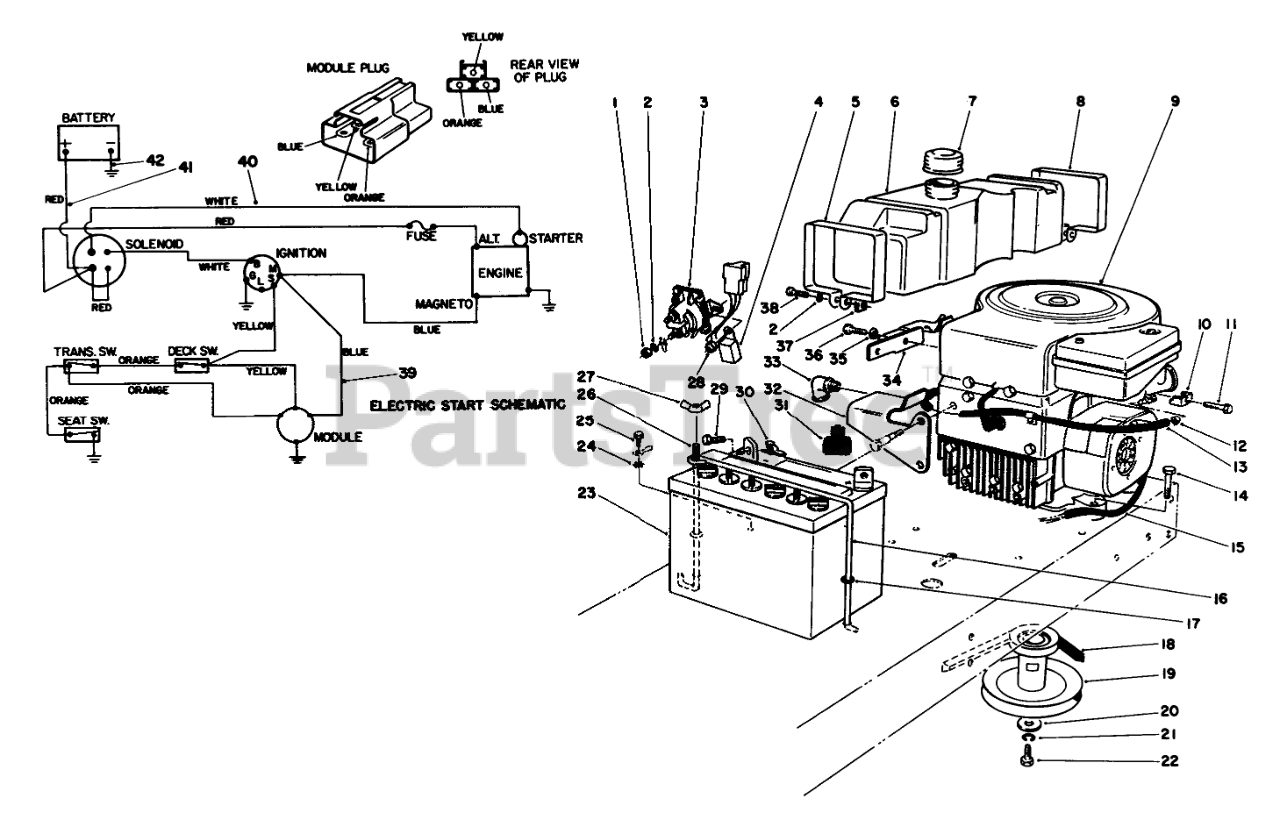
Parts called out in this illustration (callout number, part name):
1	NUT-JAM
2	WASHER-LOCK
3	SOLENOID
4	Module Interlock
5	Retainer-Front
6	TANK-5 QT GAS
7	GAS CAP ASM
8	Retainer-Rear
9	Engine
10	CLAMP-CASING
11	SCREW W ENGINE
12	FUEL HOSE CLAMP
13	HOSE-FUEL
14	SCREW-HH
15	HEAT SHRINK TUBING
16	HOLDDOWN-BATTERY
17	O-RING
18	V-BELT, TRACTION
19	PULLEY
20	WASHER-FLAT
21	WASHER-LOCK
22	SCREW-HH
23	Battery
24	WASHER-LOCK, INTERNAL
25	SCREW-HHF
26	POST-BATTERY
27	NUT-WING
28	NUT-LOCK, CONE
29	SCREW-HH
30	NUT-WING
31	BOOT-TERMINAL
32	FRT TANK MTG BRKT B
33	ELBOW-STREET, 90 DEG
34	REAR TANK MTG BRKT B
35	WASHER-PLAIN
36	SCREW-HH
37	NUT-SQUARE
38	SCREW-HSH
39	Wire Harness
40	STARTER WIRE HARNESS
41	WIRE ASM
42	WIRE ASM(BATT/GRD.
